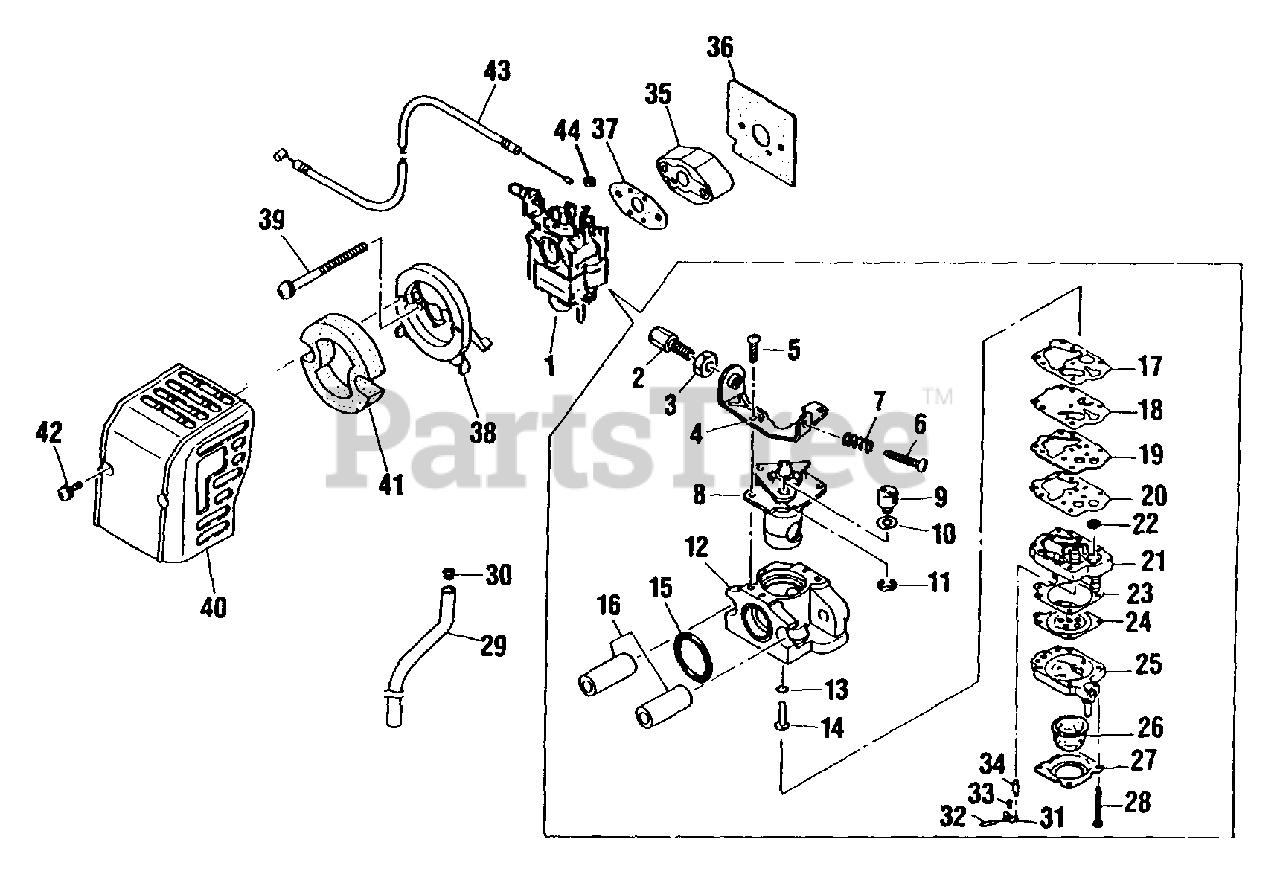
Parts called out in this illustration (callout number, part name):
1	CARBURETOR
2	NUT
2	ADJUSTER, CABLE
3	COVER, TOP
3	NUT, ADJUSTER LOCK M7
4	SPRING, THROTTLE
4	BRACKET
5	WASHER, SPRING SUPPORT
5	SCREW
6	E-RING
6	SCREW, IDLE ADJUST
7	NEEDLE JET KIT
8	VALVE, THROTTLE
8	VALVE ASSY
9	SCREW
9	SWIVEL
10	SPRING, IDLE ADJUST
10	WASHER
11	GASKET
11	E-RING
12	NUT
12	BODY
13	CLIP
13	O-RING
14	WASHER, FLAT 5.5×10×0.8
14	JET, MAIN
15	BOLT
15	RING GASKET
16	GASKET
16	SLEEVE
17	BOLT, BANJO
17	GASKET, PUMP
18	GASKET, CHAMBER
18	DIAPHRAGM, PUMP
18	DIAPHRAGM
19	JET
19	PLATE, PUMP
20	FLOAT
20	PLATE GASKET
20	GASKET
21	VALVE, INLET NEEDLE
21	PUMP BODY ASSY
22	LEVER, METERING
22	SCREEN
22	STRAINER
23	PIN
23	GASKET, METERING
23	GASKET
24	SCREW 4×6
24	DIAPHRAGM, METERING
24	DIAPHRAGM
25	SHAFT, LINK
25	BASE, PURGE
26	O-RING
26	BULB, PURGE
27	CHAMBER, FLOAT
27	RETAINER, PURGE BULB
28	SCREW 4×12
28	SCREW
29	HOSE, DRAIN
30	CLIP Ø6
31	LEVER, METERING
32	PIN, METERING LEVER
32	PIN
33	SPRING, METERING LEVER
33	LEVER, SPRING
34	VALVE, INLET NEEDLE
35	INSULATOR
36	GASKET
37	GASKET, INTAKE
38	CHOKE ASSY
39	SCREW
40	COVER, AIR FILTER
41	FILTER
42	SCREW
43	CABLE, THROTTLE
44	CLIP
